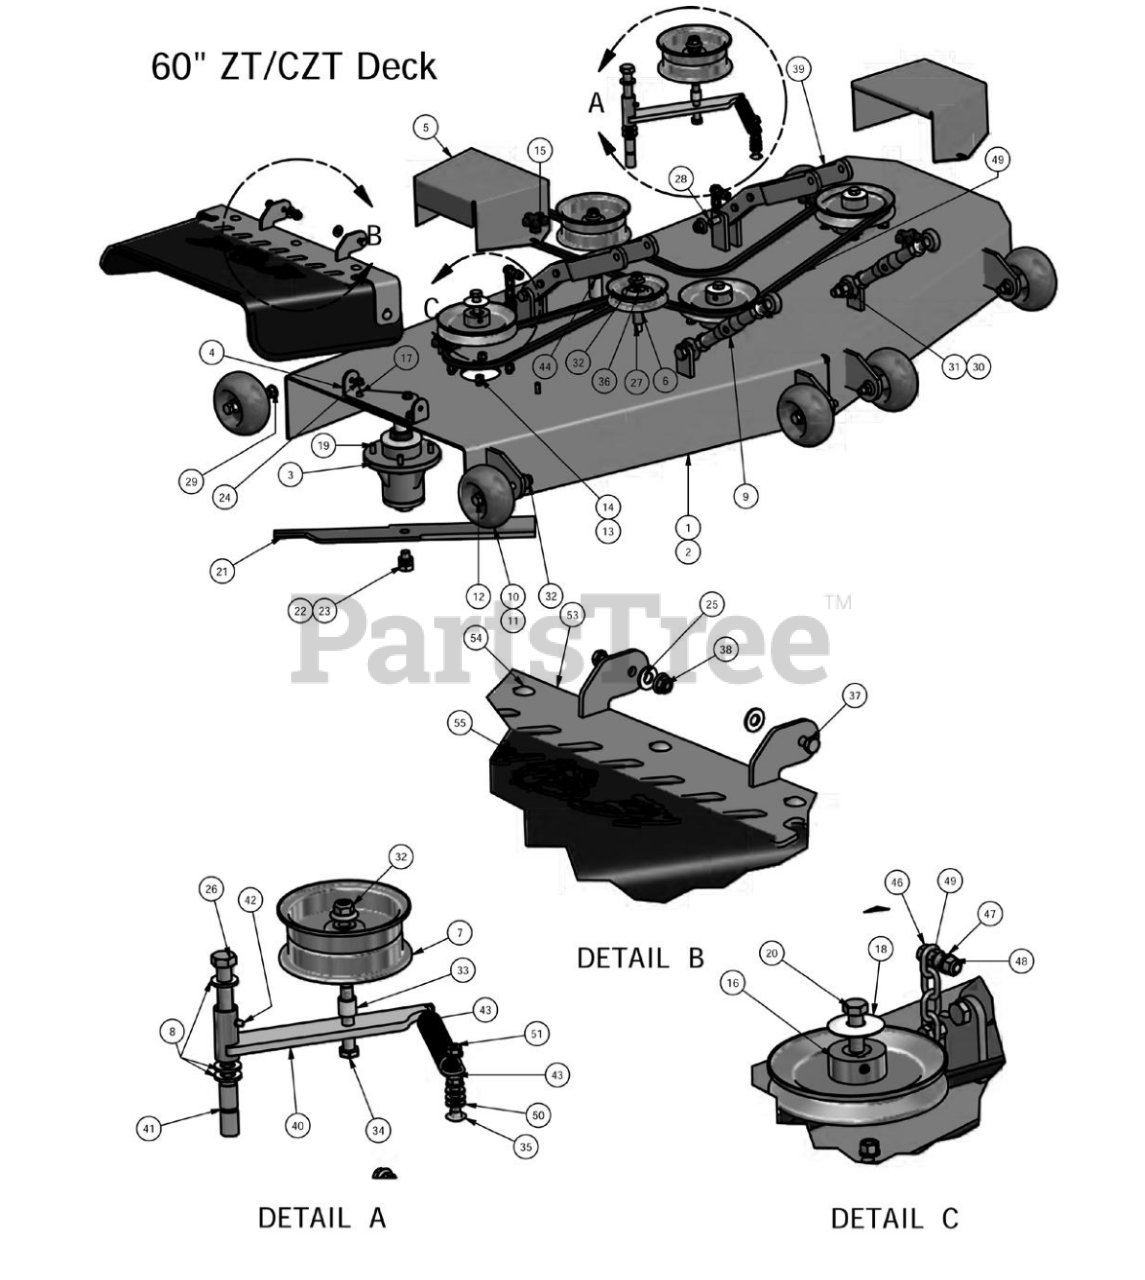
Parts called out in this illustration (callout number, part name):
1	60" ZT Deck
2	60" ZT Deck (Complete with Spindle)
3	Short Spindle
4	Discharge Chute Hanger (deck mounted)
5	Plastic Pulley Cover
6	4 3/4" Idler Pulley
7	5 3/4" Deck Idler Pulley
8	.635 ID Plastic Washer
9	Turnbuckle (Top Link)
10	Anti-Scalp Rollers
11	Deck Wheel Assembly
12	1/2" x 4" Bolt (Grade 8)
13	3/8" Lock Washer
14	3/8" Hex Nut
15	5/16" Knob
16	6 1/4" Drive Pulley
17	3/8" x 3/4" Hex Bolt
18	Cup Washer
19	3/8" x 1 1/4" Hex Bolt
20	1/2" x 1 1/2" Hex Bolt
21	60 Inch Fusion Blade
22	5/8" Lock Washer
23	5/8" x 1 1/2" Heavy Hex Bolt
24	3/8" Flange Nut
25	.360 ID Plastic Washer
26	5/8" x 4" Hex Bolt
27	Pup Pulley Spacer
28	1/2" x 2 1/2" Hex Bolt
29	1/2" Flange Nut
30	5/8" x 2 1/2" Hex Bolt
31	5/8" Std NC Nylock Nut
32	1/2-13 Nylon Flange Nut-Orange
33	3/4" OD x 1/2" ID x 3\4" Length
34	1/2" x 3" Hex Bolt
35	3/8" x 2" Carriage Bolt
36	1/2" x 3 1/2" Flange Bolt Grade 8
37	5/16" x 1" Hex Bolt
38	5/16" Nylock Flange Nut
39	Deck Arm Assembly
40	Deck Idler Bracket
41	5/8" ID x 1 1/8" Brass Bushing
42	1/4" Drive in Grease Fitting
43	Deck Idler Spring
44	1.75" x .5" O.D. Spacer
45	ZT Deck Hanger Chain Assembly
46	3/8" x 1 1/2" Hex Bolt
47	3/8" Lock Washer
48	3/8" Hex Nut
49	60" ZT Deck Belt
50	3/8" Flat Washer
51	3/8" Nylock Flange Nut
52	60" Lower Hanger
53	60" Discharge Chute Upper Hanger Plate
54	5/16" x 1 1/4" Carriage Bolt
55	Rubber Discharge Chute
